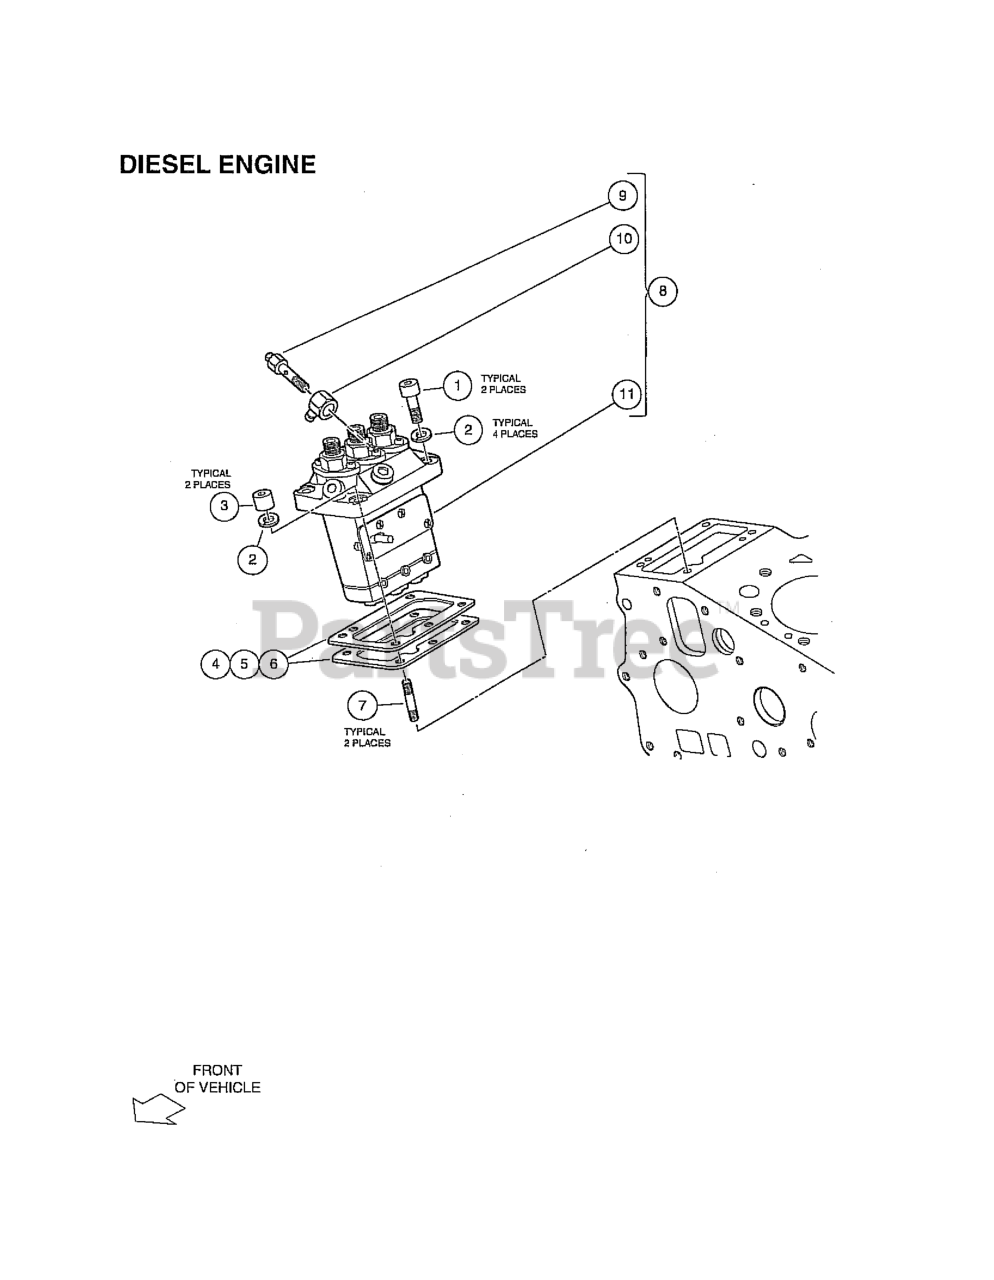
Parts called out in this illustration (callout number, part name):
1	Bolt, Hex-Head, M5 X 0.75 X
2	WASHER, SPRING, M6, D722
3	Nut, Special.
4	SHIM, INJECTION PUMP, 0.20 MM
5	SHIM, INJECTION PUMP, 0.25 MM
6	Shim, Injection Pump, 0.30 mm.
7	Stud, M5 X 25.
8	ASSY-INJ PUMP
10	Joint, Eye
